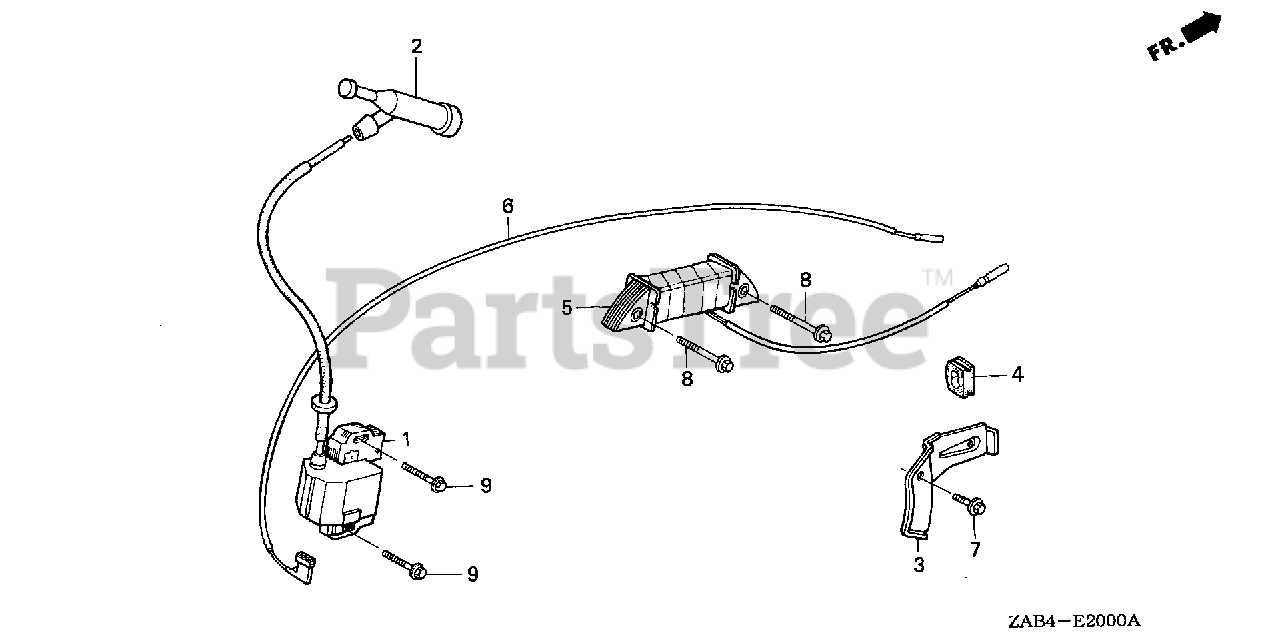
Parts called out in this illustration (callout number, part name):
1	COIL ASSY., IGNITION
2	CAP ASSY., NOISE SUPPRESSOR (NICHIWA Y-EZ RTFM256)
3	CLAMP, WIRE
4	GROMMET, WIRE
5	COIL ASSY., CHARGE
6	WIRE, STOP SWITCH (470MM)
7	BOLT, FLANGE (6X12) (CT200)
8	BOLT, FLANGE (6X35)
9	BOLT, FLANGE (6X28)
